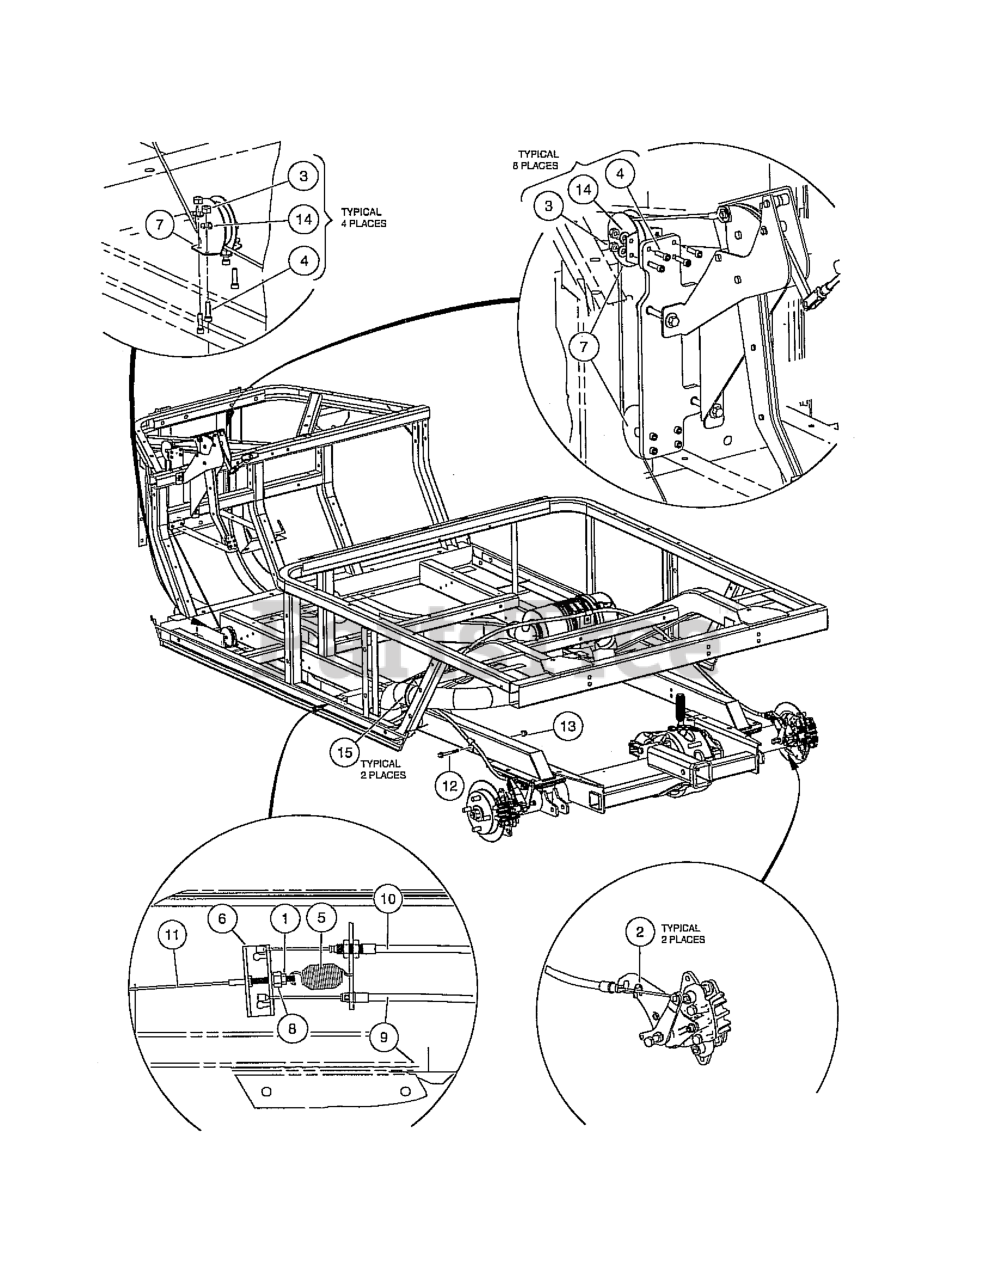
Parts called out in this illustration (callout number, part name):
1	NUT, 5/16-24 HEX
2	E-CLIP, 1/2
4	SCREW, #10-24 X 3/4 SOCKET HD
5	SPRING, BRAKE RETURN
6	EQUALIZER BRACKET, PREC
8	NUT, 5/16-24 HEX CONE
9	CABLE, BRAKE, PARKING, LEFT
10	CABLE, BRAKE, PARKING, RIGHT
11	CABLE, BRAKE, PARKING, FRONT
12	BOLT FLG, M8X1.25X65
13	LOCK NUT, FLG M8 X 1.25 NYLON
14	WASHER FLAT
15	TIE WRAP , 11" NYLON
